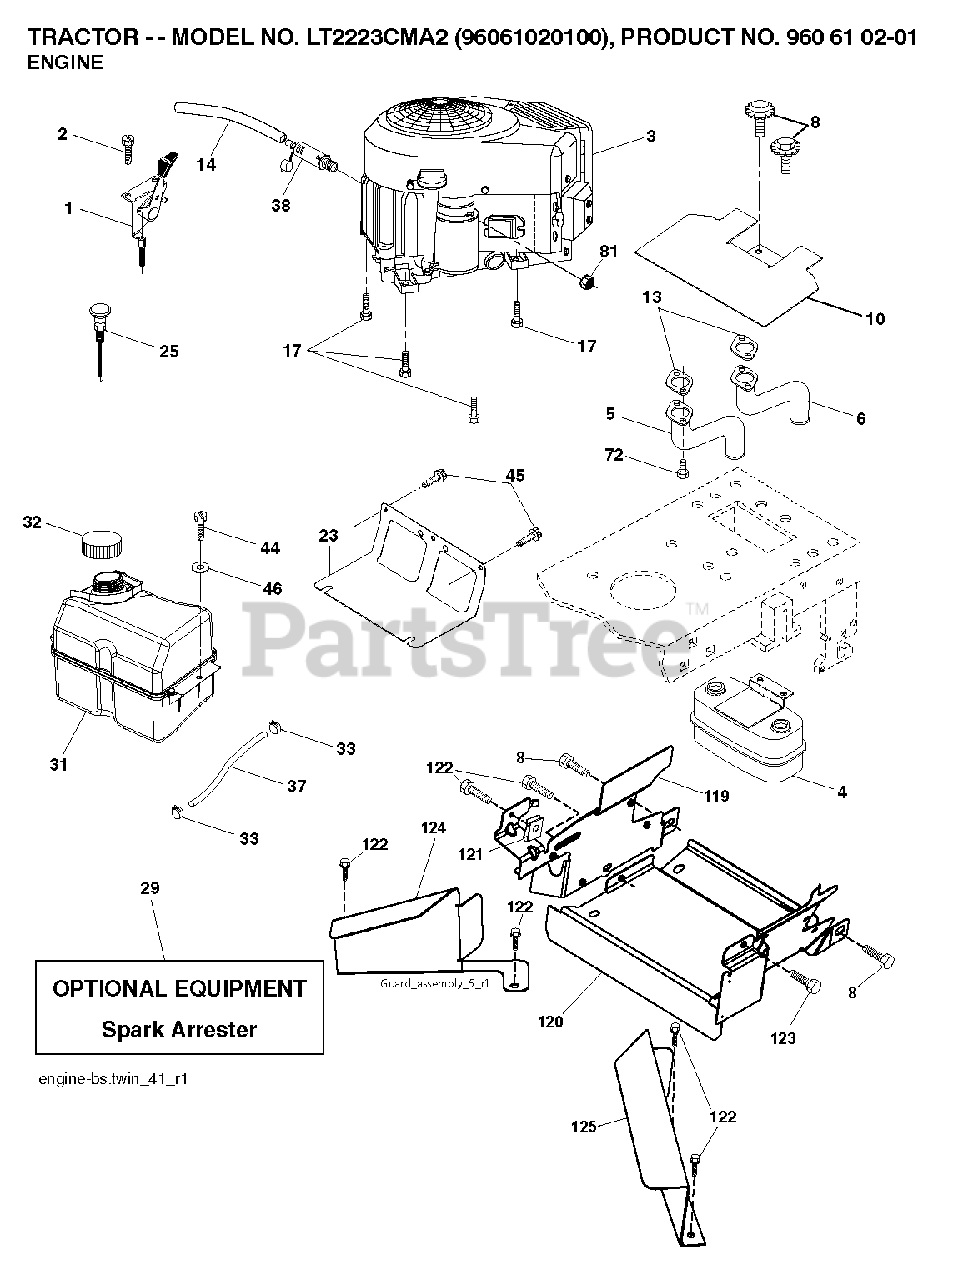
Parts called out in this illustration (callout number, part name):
1	THROTTLE CABLE
2	SCREW
4	MUFFLER.TWIN.CYL.LOW.TONE
5	EXHAUST TUBE RH
6	TUBE MANIFOLD LH
8	BOLT, 5/16-18 X 1 3/4
10	RP SHIELD HEAT MUFFLER
13	GASKET.MUFFLER
14	TUBE, DRAIN OIL ASM.
17	SCREW.3/8-16
23	SHEILD.BROWNING.DBR.GUARD
25	CONTROL CHOKE
29	ARRESTER SPARK (OPTIONAL)
31	FUEL TANK FRT 2 GAL.
32	FUEL CAP
33	HOSE CLAMP
37	LINE.FUEL.20
38	PLUG DRAIN OIL EASY
44	SCREW HEXWSHR 1/4-20X3/4
45	SCREW, 3/8-16X3/4
72	SCREW.SOCKET.HEAD.5/16-18
81	NUT
122	SCREW.1/4-20X5/8
123	SCREW, 5/16-18 X 1/2
